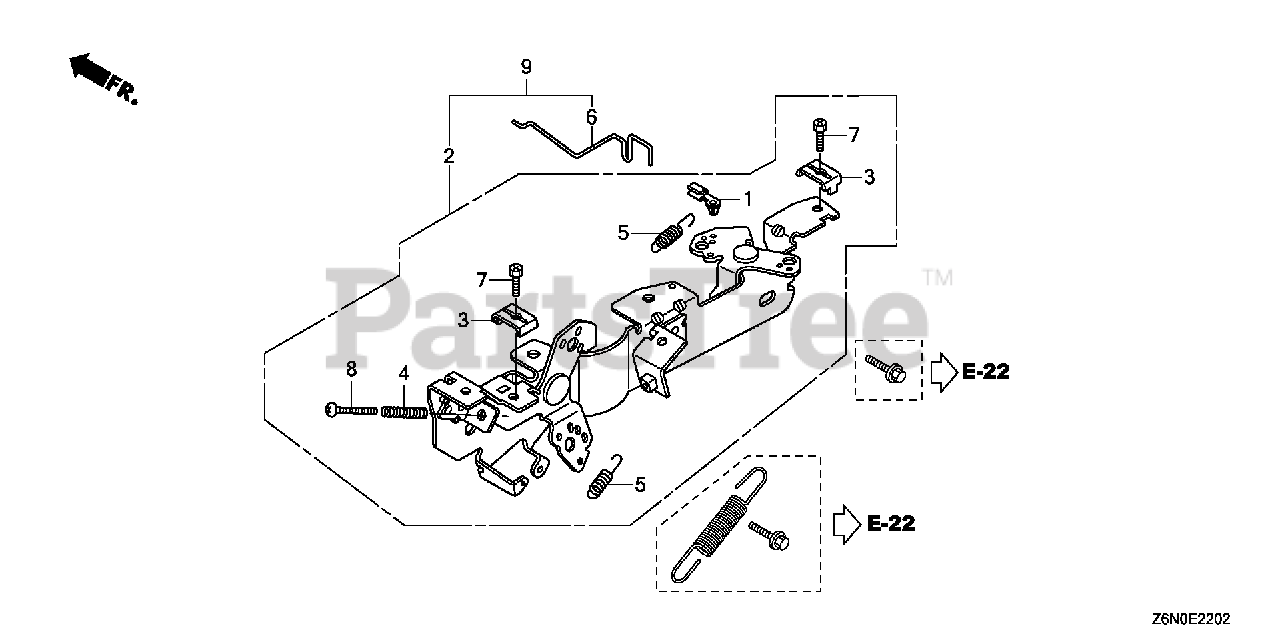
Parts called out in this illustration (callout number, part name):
1	JOINT, ROD
2	CONTROL ASSY.
3	HOLDER, CABLE
4	SPRING, CONTROL ADJUSTING
5	SPRING, CABLE RETURN
7	BOLT, RECESSED (5X16)
8	SCREW, PAN (5X40)
